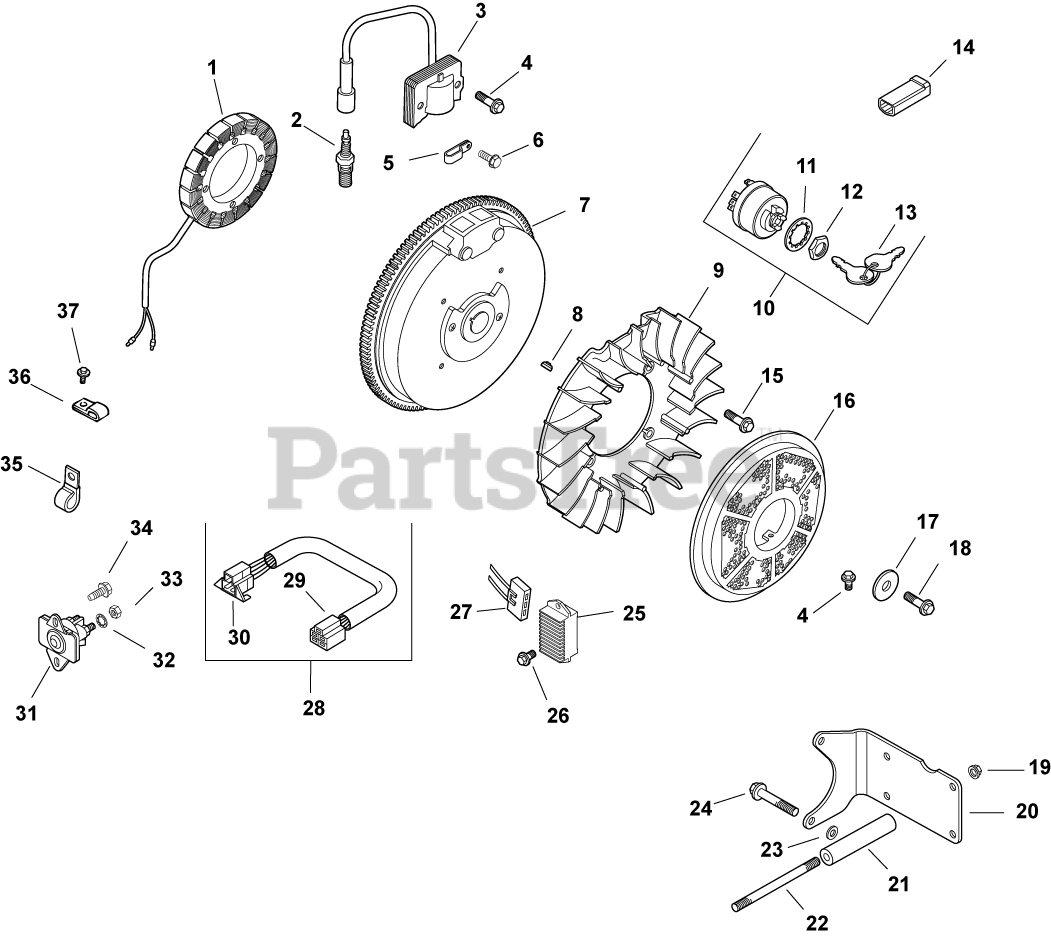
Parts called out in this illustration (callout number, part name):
1	KIT, 25 AMP STATOR ASSY.
2	PLUG, SPARK (PRO SERIES)
3	MODULE, IGNITION
4	SCREW, FLG THD FRM M5X.8X20-(#25086399S)
6	SCREW, FLG THD FRM M5X.8X10
8	KEY, 3/16" X 5/8"
9	FAN - DISCONTINUED
10	SWITCH ASSY, KEY (KM)-USE 25 099 32-S
11	WASHER, INTERNAL TOOTH
12	NUT, KEY SWITCH
13	KEY, SET -USE 48 340 01-S
14	CONNECTOR (1 CONTACT)
15	BOLT, SHOULDER
16	SCREEN, GRASS
17	WASHER, FLAT 13/32"
18	SCREW, FLG M10X1.5X45 - (#25086361S)
19	NUT, FLG M8X1.25
20	BRACKET, FUEL TANK
22	STUD, M8X1.25X133-USE 25 755 54-S
23	WASHER, FLAT 11/32"
24	SCREW, FLG M8X1.25X45
25	REG/RECTIFIER (20/25 AMP)-USE 25 403 20-
26	SCREW, FLG M6X1.0X16
27	CONNECTOR, BODY (KM)-USE 25 155 41-S
28	CONNECTOR ASSEMBLY
29	CONNECTOR
30	CONNECTOR
31	SOLENOID - WATERPROOF (KM)-USE 25 435 08
32	WASHER, INT TOOTH LOCK 1/4"
33	NUT, JAM 1/4-20 GRADE 2
34	SCREW,FLG THD FRM M6X1.0X16-(#25086397S)
35	CLIP, CABLE
36	CLIP, TUBE & WIRING (KM)
37	SCREW, THD FROM M5X0.8X30
